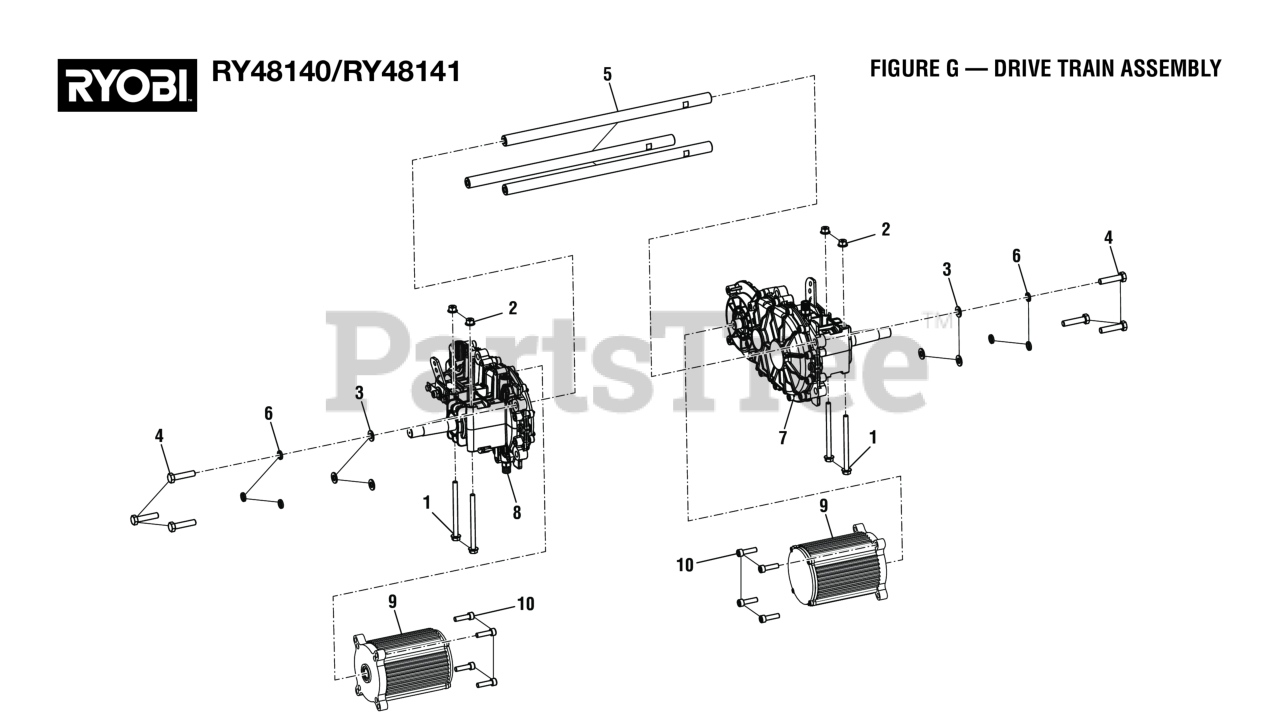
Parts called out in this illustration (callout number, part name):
1	Flange Bolt (M8 x 110 mm, Hex Hd.)
2	Flange Nut (M8) (For Drive Motor Controller V)
3	Washer (OD20 x ID10.5 x 2t)
4	Bolt (M10 x 45 mm, Hex Hd.)
6	Lock Washer (M10)
7	Gearbox, Left
8	Gearbox, Right
9	Drive Motor
10	Screw (M8 x 30 mm, Soc Hd.)
